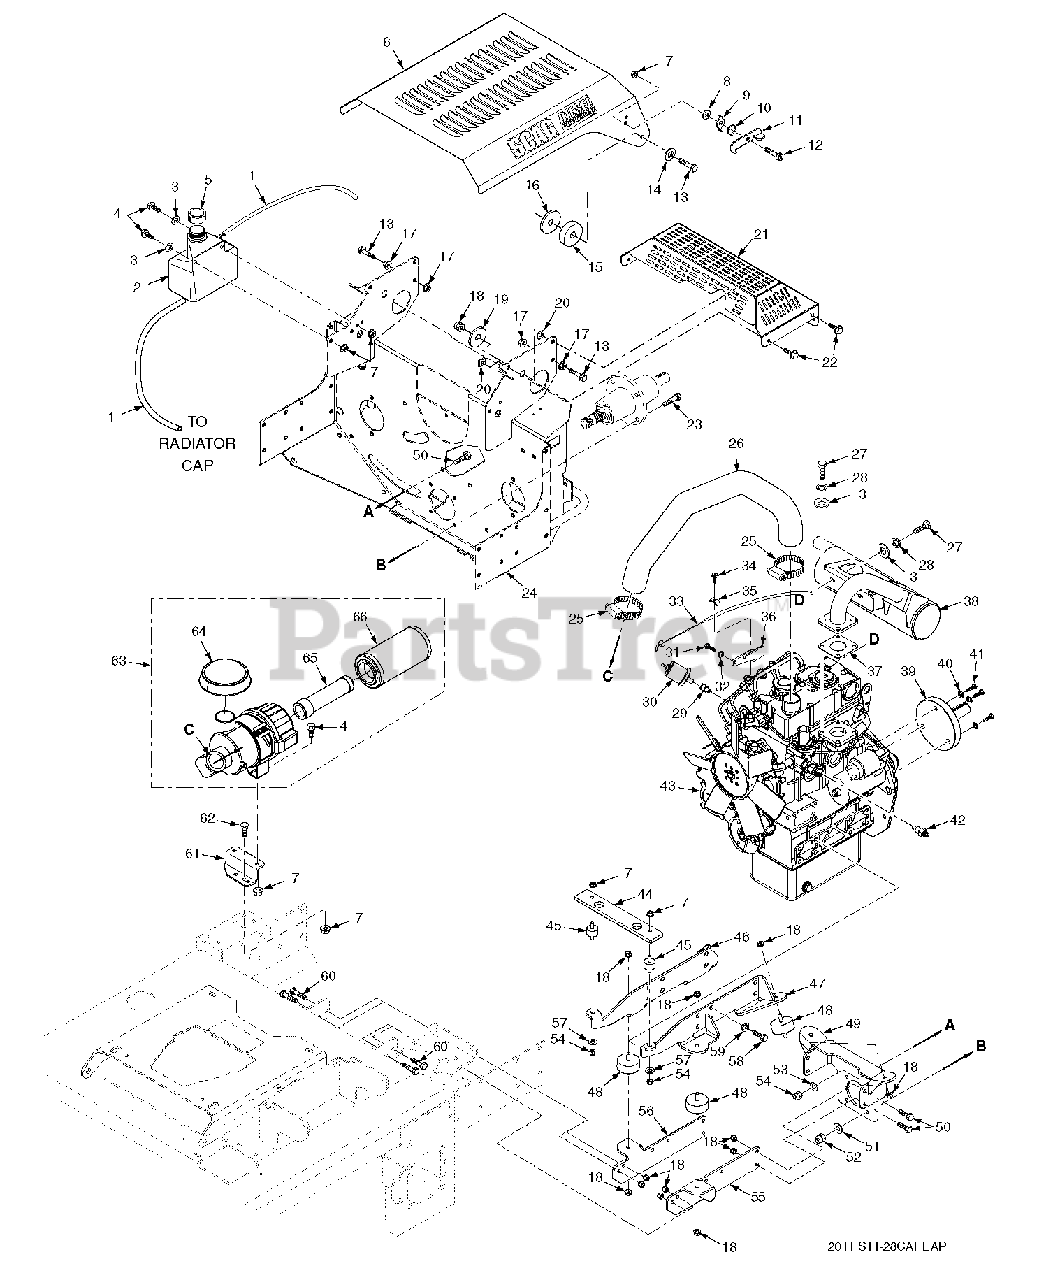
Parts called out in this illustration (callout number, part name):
1	Hose, Coolant Resrvoir Bottle
2	Coolant Reservoir Bottle
3	Flatwasher, SAE 5/16-.344 x .688 x .065
4	Bolt, Hex Head Serr. Flng 5/16-18 x 3/4"
5	Cap, Coolant Reservoir Bottle
6	Hood Assembly w/Decals
7	Nut, Serrated Flange 5/16-18
8	Flatwasher, 3/8-.406 x .812 x .065
9	Lock, Hood Latch
10	Spring, Hood Latch
11	Latch, Hood
12	Bolt, Shoulder 5/16-18 x 1/2"
13	Bolt, Hex Head 3/8-16 x 1-3/4"
14	Flatwasher, 3/8-.391 x .938 x .105
15	Spacer, Hood
16	Disc, Anti Friction
17	Nut, Serrated Flange 3/8-16
18	Nut, Elastic Stop 3/8-16
19	Flatwasher, 3/8-.406 x 1.50 x 7 Gauge
20	U-Nut, 1/4"-20
21	Muffler Guard
22	Bolt, Hex Head Serrated Flange, 1/4-20 x 3/4"
23	Bolt, Hex Head 5/16-18 x 1-3/4" Grd 8
24	Pump Mounting Plate Weldment
25	Clamp, 2-1/4" Max. Dia.
26	Hose, Air Intake
27	Bolt, Hex Head M8-1.25 x 20
28	Lockwasher, 5/16" Spring
29	Elbow, 45 Degree
30	Oil Pressure Sender
31	Bolt, Hex Head M6-1.0 x 16
32	Lockwasher, 1/4" Spring
33	Throttle Cable
34	Screw, Self Tapping
35	Clamp
36	Mounting Bracket, Throttle Cable
37	Gasket, Muffler
38	Muffler, Cat Diesel
39	Stub Shaft
40	Lockwasher, 7/16" Spring
41	Bolt, Hex Head M10 x 1.5 x 35
42	Temperature Sensor, Engine Coolant
44	Mount, Radiator
45	Mount, Radiator Isolation
46	Mounting Bracket Weldment RH
47	Mounting Bracket Weldment LH
48	Mount, Engine Isolation
49	Plate, Rear Engine Mount
50	Bolt, Hex Head 3/8-16 x 1"
51	Flatwasher, 5/16" (.375 x .875 x .083)
52	Nut, Elastic Stop 5/16-18 Grade 8
53	Lockwasher, 3/8" Spring
54	Nut, Elastic Stop 3/8-16
55	Plate, Engine Mount LH
56	Plate, Engine Mount RH
57	Flatwasher, 3/8" (.406 x 1.50 x 7 ga)
58	Bolt, Hex Head M12-1.25 X 25mm
59	Lockwasher, 1/2" Spring
60	Bolt, Hex Head 3/8-16 x 1"
61	Bracket, Air Cleaner Mount
62	Bolt, Carriage 5/16-18 x 3/4"
63	Air Filter Assembly
64	Rain Cap
65	Air Filter, Inner
66	Air Filter, Outer
